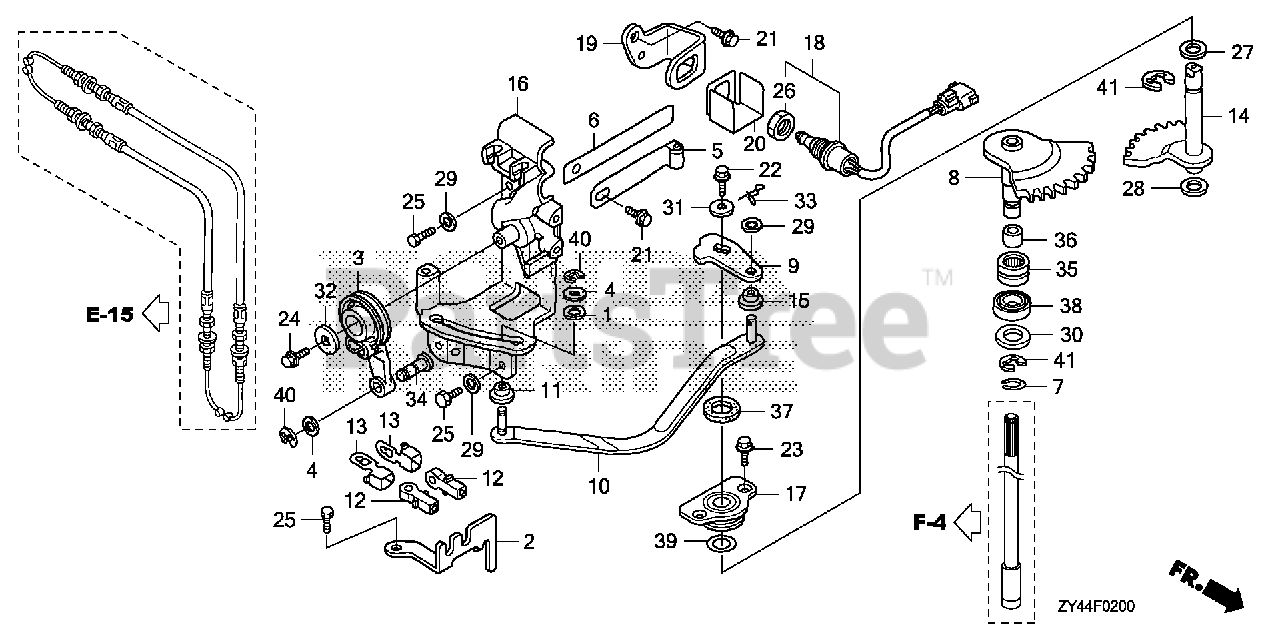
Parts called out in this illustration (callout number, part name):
1	WASHER, AIR CLEANER COVER SETTING
2	PLATE, REMOTE CONTROL CABLE
3	ARM, THROTTLE
4	WASHER, PIVOT
5	SPRING, CLICK
6	SPRING, CLICK ASSIST
7	RING, STOPPER
8	SHAFT, SHIFT (A)
9	ARM, SHIFT
11	COLLAR, SHIFT SLIDER
12	PIVOT, SHIFT
13	PLATE, LOCK
14	SHAFT, SHIFT (B)
15	BUSH, SHIFT ARM
16	BRACKET, SHIFT LINK
17	HOLDER, SEAL
18	SWITCH ASSY., NEUTRAL
19	BRACKET, NEUTRAL SWITCH
20	COVER, NEUTRAL SWITCH
21	BOLT, FLANGE (6X14) (CT200)
22	BOLT, FLANGE (6X16)
23	BOLT, FLANGE (6X11)
24	BOLT, FLANGE (6X12)
25	BOLT, HEX. (6X16)
26	NUT, HEX. (20MM)
27	WASHER, THRUST (14MM)
28	WASHER, SHIFT SHAFT
29	WASHER, PLAIN (6MM)
31	WASHER, PLAIN (6MM)
32	WASHER, PLAIN (6MM)
33	PIN, SNAP (6MM)
35	BEARING, NEEDLE (20X28X13) (SOLID)
36	RING (INNER) (15X20X13)
37	OIL SEAL (14X26X6)
38	SEAL, WATER (14X26X8)
39	O-RING (26.9X2.4) (NOK)
40	E-RING (4MM)
41	E-RING (12MM)
